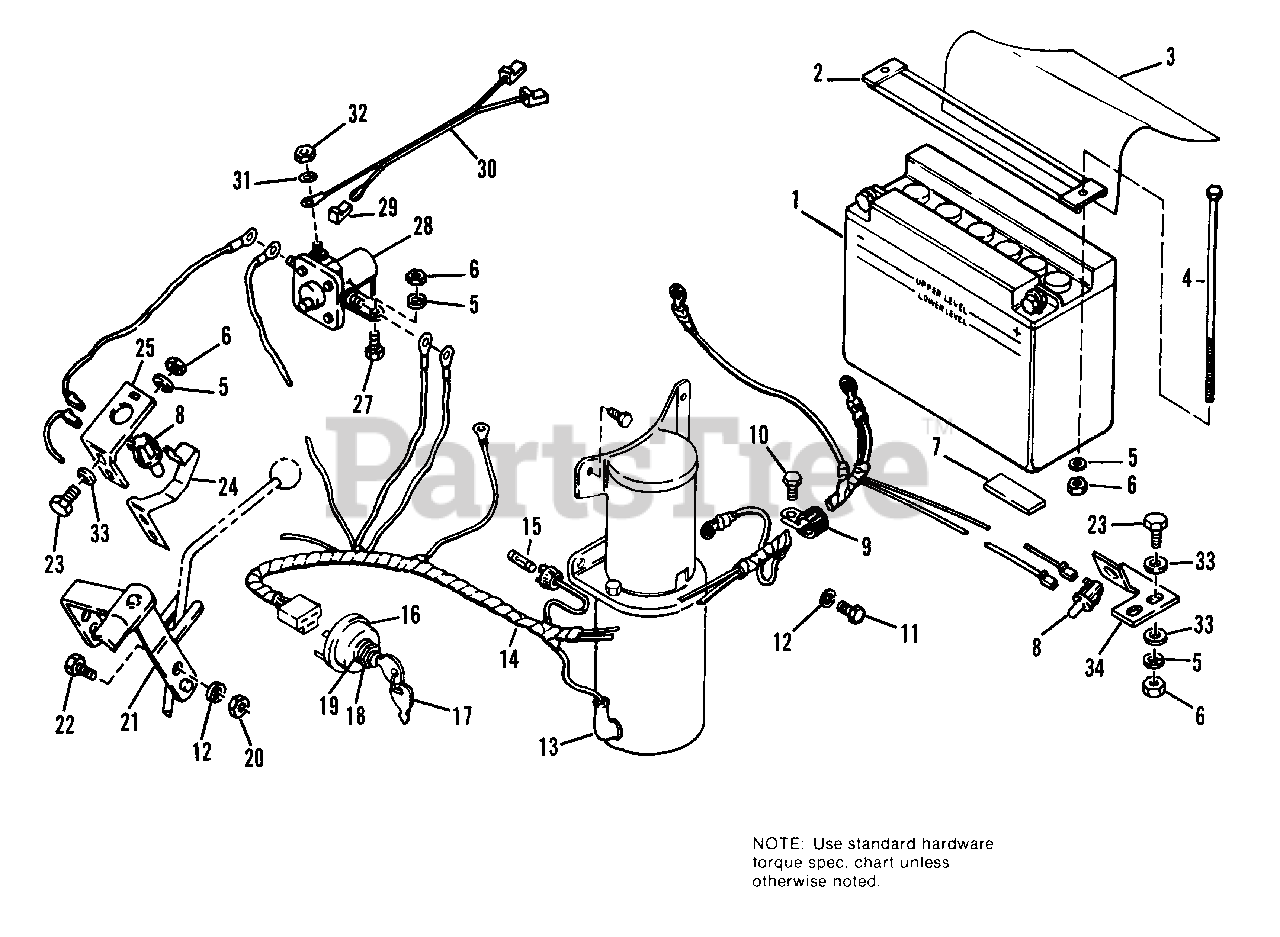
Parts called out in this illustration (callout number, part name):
2	HOLD DOWN, Battery
3	INSULATION, Battery
4	CAPSCREW, Hex Hd., 1/4-20 x 7
5	LOCKWASHER, 1/4
6	NUT, Hex, Full, 1/4-20
7	GASKET, Felt
10	SCREW, Hex, Taptite, #10-24 x 1/2
11	CAPSCREW, Hex Hd., 5/16-18 x 5/8
12	LOCKWASHER, 5/16
13	COVER, Terminal
14	HARNESS ASSY.
16	SWITCH, Starter W/Keys
18	NUT, Hex, Special
19	LOCKWASHER, Int., 9/16
20	NUT, Hex, Full, 5/16-18
21	PIVOT ASSY.
22	CAPSCREW, Hex Hd., 5/16-18 x 3/4
23	CAPSCREW, Hex Hd., 1/4-20 x 3/4
24	CLIP, Spring
26	LOCKNUT, Flange, Hex, 1/4-20
27	SCREW, Hex, Taptite, 1/4-20 x 3/8
29	CONNECTOR, Insulated
31	LOCKWASHER, Ext., #10
32	NUT, Hex, Full, #10-32
33	WASHER, Plain, 3/16
